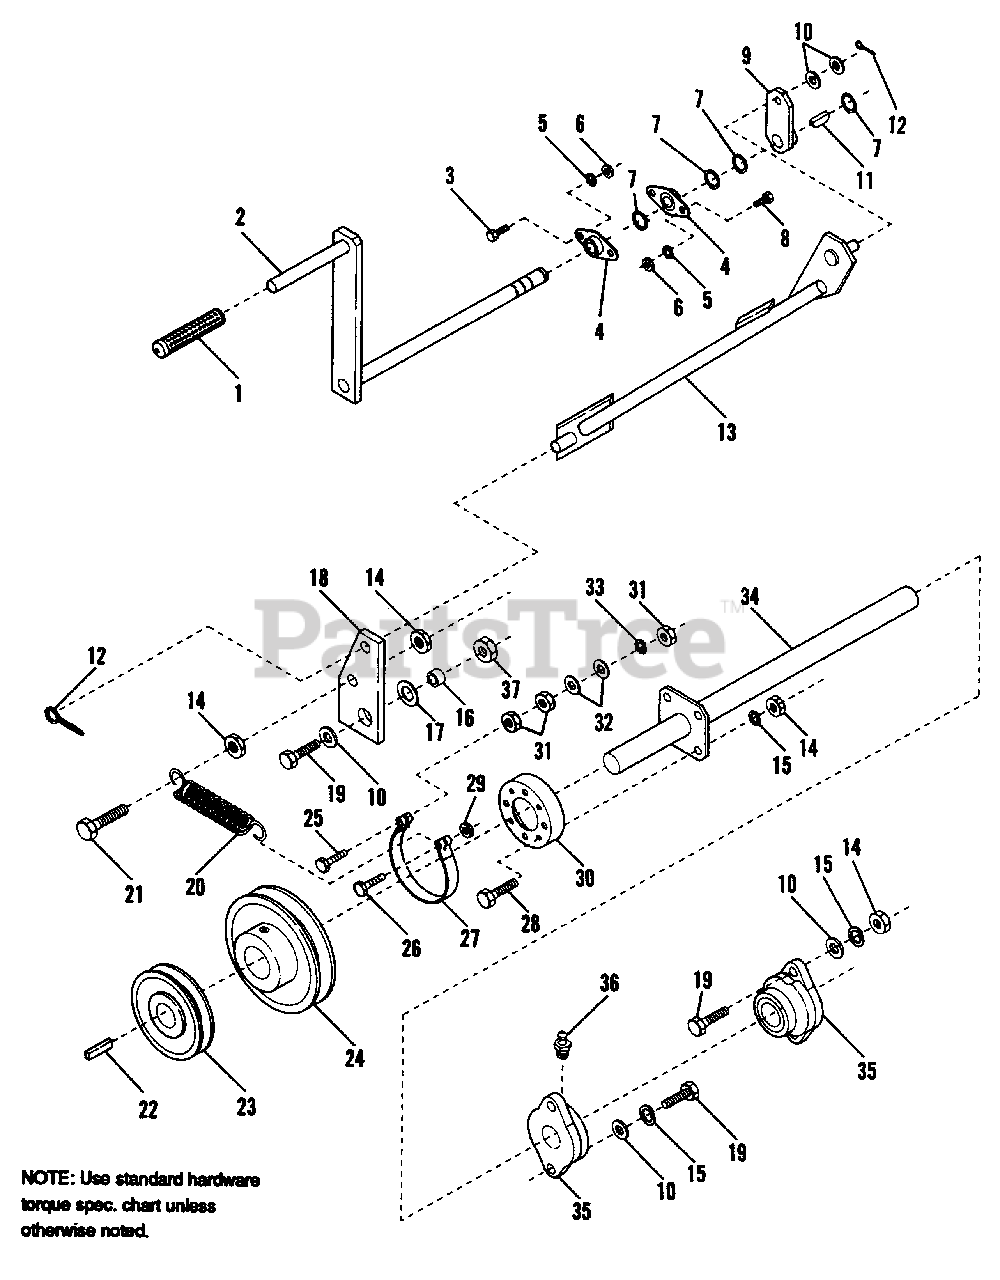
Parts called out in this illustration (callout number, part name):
2	PTO HANDLE ASSY.
3	CAPSCREW, Hex 1/4-20 x 1/2
4	BEARING, Flanged
5	LOCKWASHER, Spring 1/4
6	NUT, Hex 1/4-20
7	RING, Retaining, External 5/8
8	CAPSCREW, Hex 1/4-20 x 3/4
10	WASHER, Plain
11	KEY, Woodruff 3/16 x 3/4
14	NUT, Hex 5/16-18
15	LOCKWASHER, Spring 5/16
17	WASHER, Plain
18	ARM, Brake
19	CAPSCREW, Hex 5/16-18 x 1-1/4
20	SPRING, Tension
21	CAPSCREW, Hex 5/16-18 x 1-1/2
22	KEY, Square 1/4 x 2-1/4
23	V-PULLEY, PTO
24	V-PULLEY, PTO
25	CAPSCREW, Hex 3/8-16 x 2-1/2
26	CAPSCREW, Hex 3/8-16 x 1-1/2
27	BAND, Brake
28	CAPSCREW, Hex 5/16-18 x 3/4
29	LOCKNUT, Hex 3/8-16
30	DRUM, Brake
31	NUT, Hex 3/8-16
32	WASHER, Plain
33	LOCKWASHER, Spring 3/8
34	JACKSHAFT ASSY.
35	BEARING, Collared
36	FITTING, Grease
37	LOCKNUT, Hex, Flanged 5/16-18
